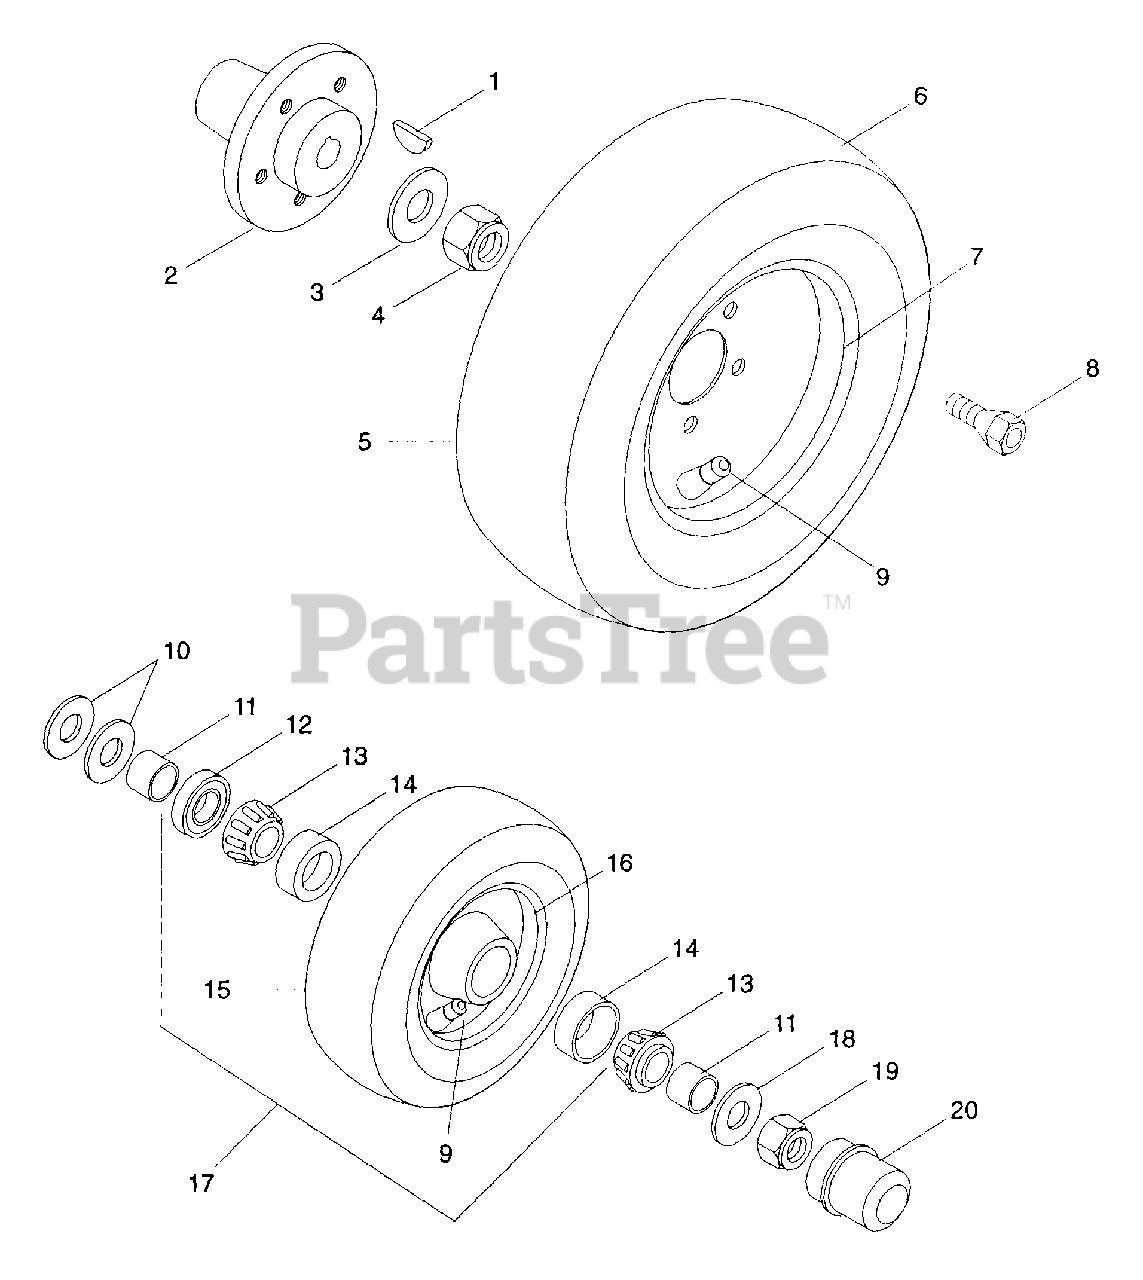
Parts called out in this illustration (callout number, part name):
1	Key, Woodruff .25 x 2.13
2	Hub, Tapered 4-Wheel
3	Washer-Flat-Steel .813 x 2.000 x .148
4	Nut-Locking-Nylon .75-10 Grade 2
5	Tire/Wheel Assembly 23 x 8.5-12
5	Tire/Wheel Assembly 23 x 10.50-12
6	Tire, Rear 23 x 8.50-12
6	Tire, Rear 23 x 10.50-12
7	Weldment, Rim
8	Bolt .44-20 x 1.0
9	Valve Stem Assembly
10	Washer-Flat-Steel .813 x 1.370 x .100
11	Spacer
12	Seal 1.206 x 1.785 x .468
13	Bearing/Cone .750 x .61
14	Bearing/Cup 1.781 x .475
15	Tire, Front 16 x 6.50-8
15	Tire, Front 16 x 7.50-8
16	Weldment, Rim
17	Tire/Wheel Assembly 16 x 6.5 x 8
17	Tire/Wheel Assembly 16 x 7.50-8
18	Washer-Flat-Steel .656 x 1.312 x .095
19	Nut-Locking-Nylon .625-11 Grade 2
20	Dust Cap
